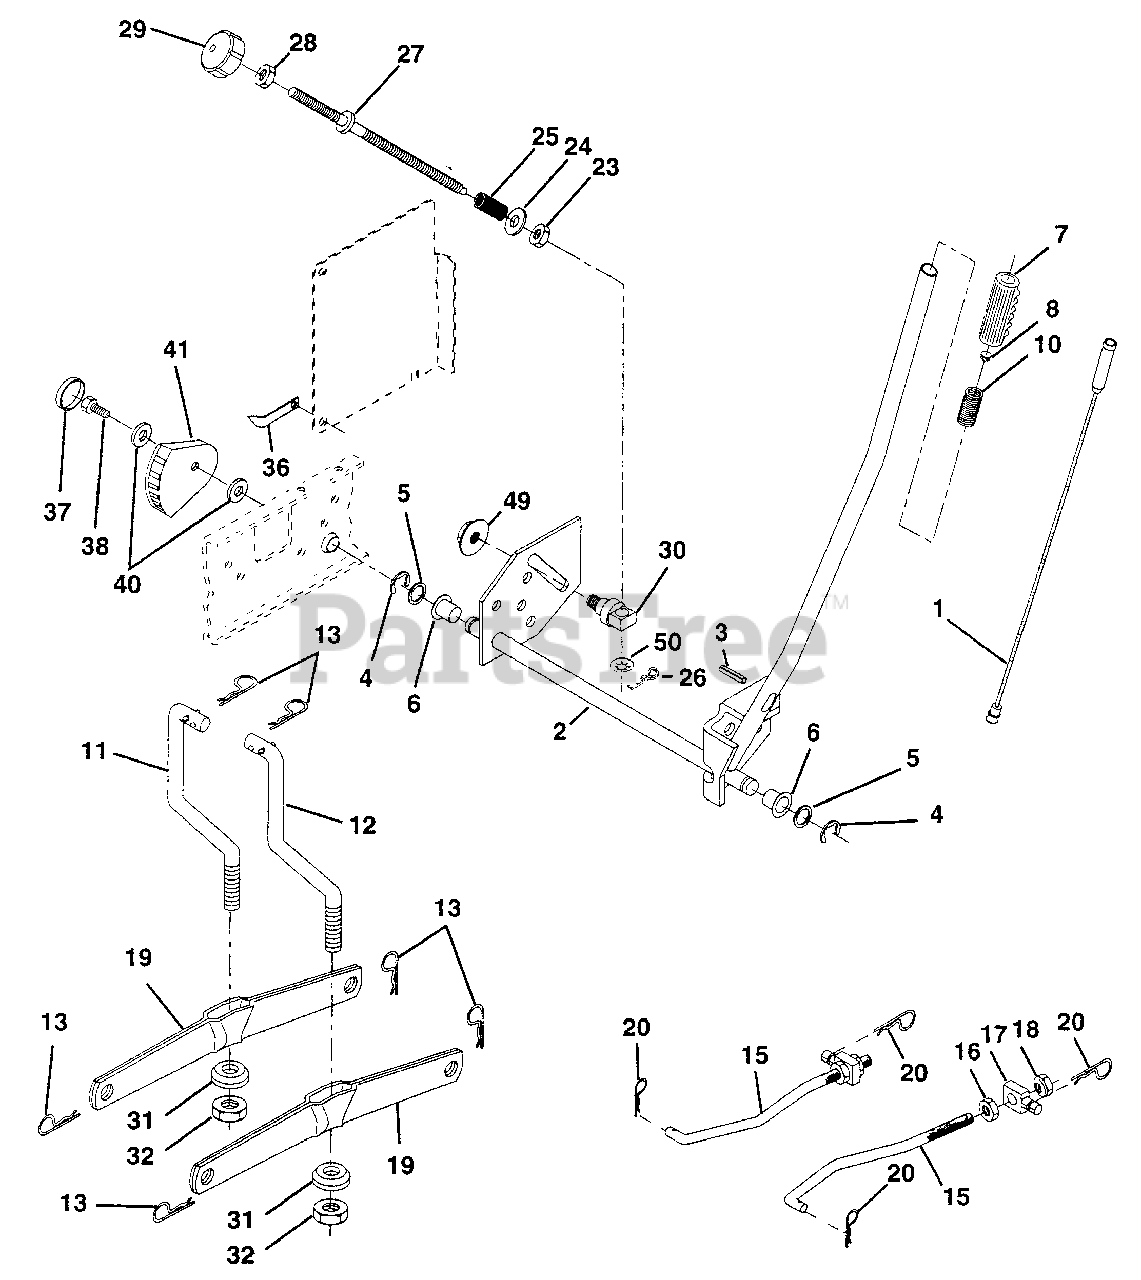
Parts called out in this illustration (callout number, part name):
1	Wire Asm Inner W/plunger 17.32
2	Shaft Asm Lift RH w/Inf
3	Pin Groove 1 500 Zinc
4	E Ring #5133-62
5	Washer 21/32 X 1 X 21 Ga
6	Bearing Nylon Blk 629 Id
7	Grip Handle Fluted Blk
8	Button Plunger Black
10	Spring Cprsn 3 750 Oiled
11	Link Lift LH Fixed Length
12	Link Lift RH Fixed Length
13	Retainer Spring
15	Link Front
16	Nut Jam Hex 1/2-13 Unc
17	Trunnion Blk Zinc
18	Nut Lock W/wsh 1/2-13 unc
19	Arm Suspension Rear
20	Retainer Spring
23	Nut Special
24	Washer 13/32 X 5/8 X 16 Ga
25	Spring 2-1/8"
26	Pin Cotter 3/32 X 1/2
27	Rod Adj Lift Zinc 7.49 Wrk Lg
28	Nut Hex Jam 3/8-16 Unc
29	Knob Inf 3/8-16 Unc Blk W/sym
30	Trunnion Infin Height
31	Bearing Pvt Lift Spherical
32	Nut Crownlock 3/8 - 24
36	Indicator Height STLT
37	Plug Hole Blk 1.485/1.515 Dia.
38	Screw Thdrol 5/16-18 x 3/4
40	Washer 11/32 x 1-1/2 10 Ga.
41	Scale Ind. Height Blk.
49	Nut Hex Flange Lock
50	Nut Push Phos & Oil
